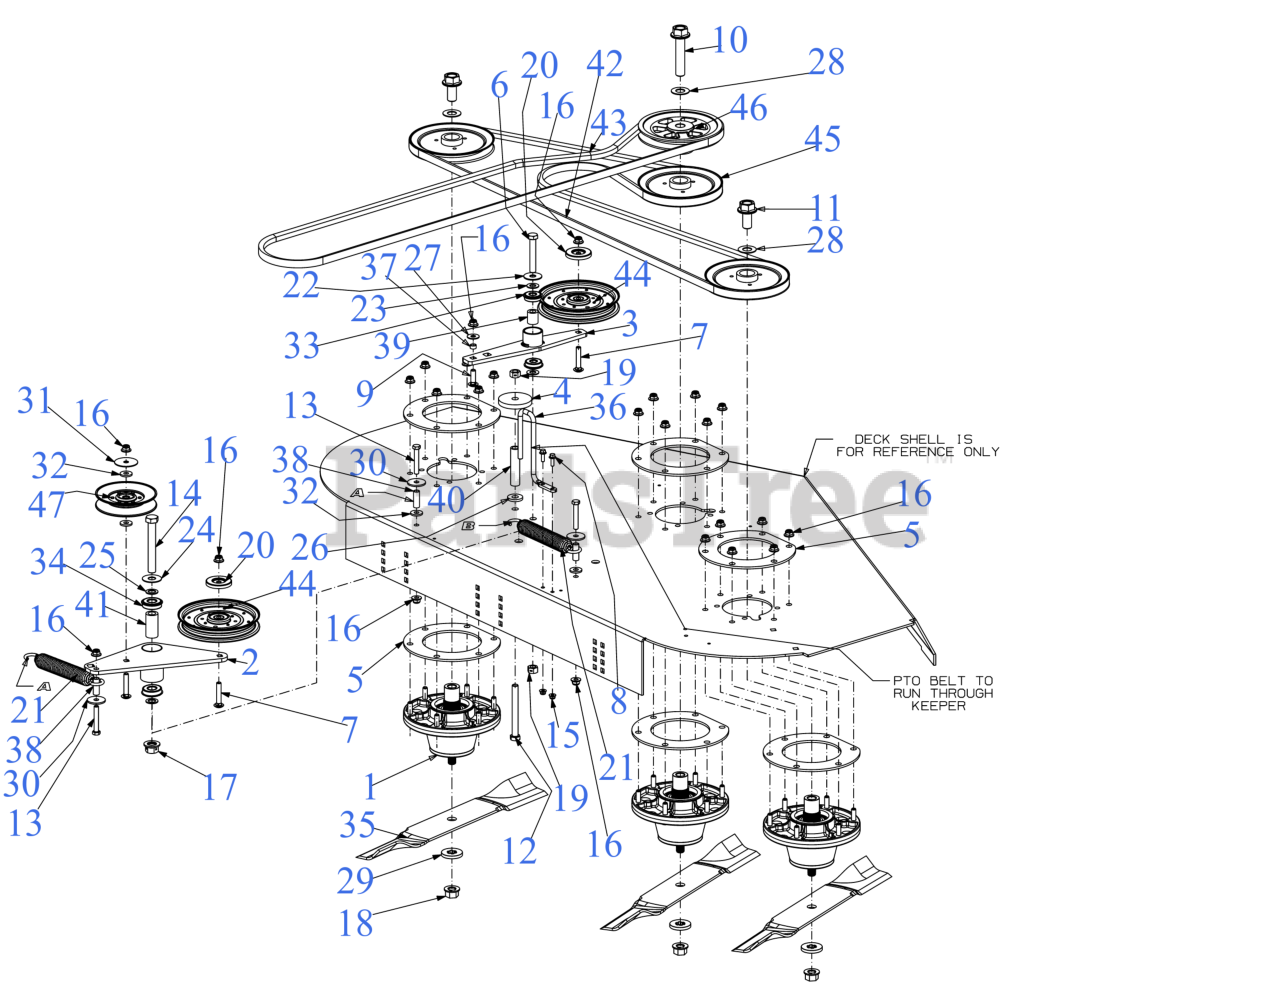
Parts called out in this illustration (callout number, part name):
1	SPINDLE ASSEMBLY
4	SPACER PLATE
5	SPINDLE SUPPORT BRACKET TOP/BTM
6	SCREW-HEX 1/2-13 x 3.00
7	CARRIAGE BOLT 3/8-16 x 2
8	SCREW 1/4-20 x .75 GR5
9	CARRIAGE BOLT 3/8-16 X1.25 GR5
10	CAP SCREW-HHFLG 3/4-10 X 3.50 GR8
11	CAP SCREW-HHFLG 3/4-10 X 1.50 GR8
12	SCREW 1/2-13 x 4.5 GR 5
13	SCREW 3/8-16 x 2.25 GR5
14	SCREW 5/8-18X4.5 GR5
15	FLANGE LOCK NUT
18	FLANGE NUT - 5/8-18 GDE 8
19	HEX NUT CTR LK 1/2-13
20	PULLEY CAP
21	SPRING 1.25" DIA x 8.5" LONG
22	FLAT WASHER
23	FLAT WASHER .510X.995
24	FLAT WASHER-.63IDX1.595ODX.62
25	FLAT WASHER
26	FLAT WASHER .531 x 1.25 x .181
27	WASHER-.395 x 1.0 x .62
28	FLAT WASHER
29	FLAT WASHER - SPECIAL
30	FLAT WASHER .406X1.5X11
31	HUB CAP WASHER .406 x 1.92 x .060
32	FLAT WASHER .406ID X1.0 OD
33	ROLLER BEARING .5X1.37X.44
34	BALL BEARING W/RET
35	21" BLADE (HI LIFT)
35	Cub Cadet 60" BLADE SET
35	Genuine Factory Parts 60" BLADE SET
35	LOW-LIFT 21"BLADE (60"DECK)
35	BLADE-HI LIFT 21.0
35	BLADE-21"MULCH 60"
35	21" XTREME BLADE
39	SPACER 0.51 x 0.88 x 1.00
41	SPACER 0.63 x 1.00 x 2.01
43	V-BELT B SEC x 105.15
44	IDLER PULLEY
45	SPINDLE PULLEY 7"
46	PULLEY-7.01 OD x .75 ID
47	IDLER PULLEY 5.06 OD
